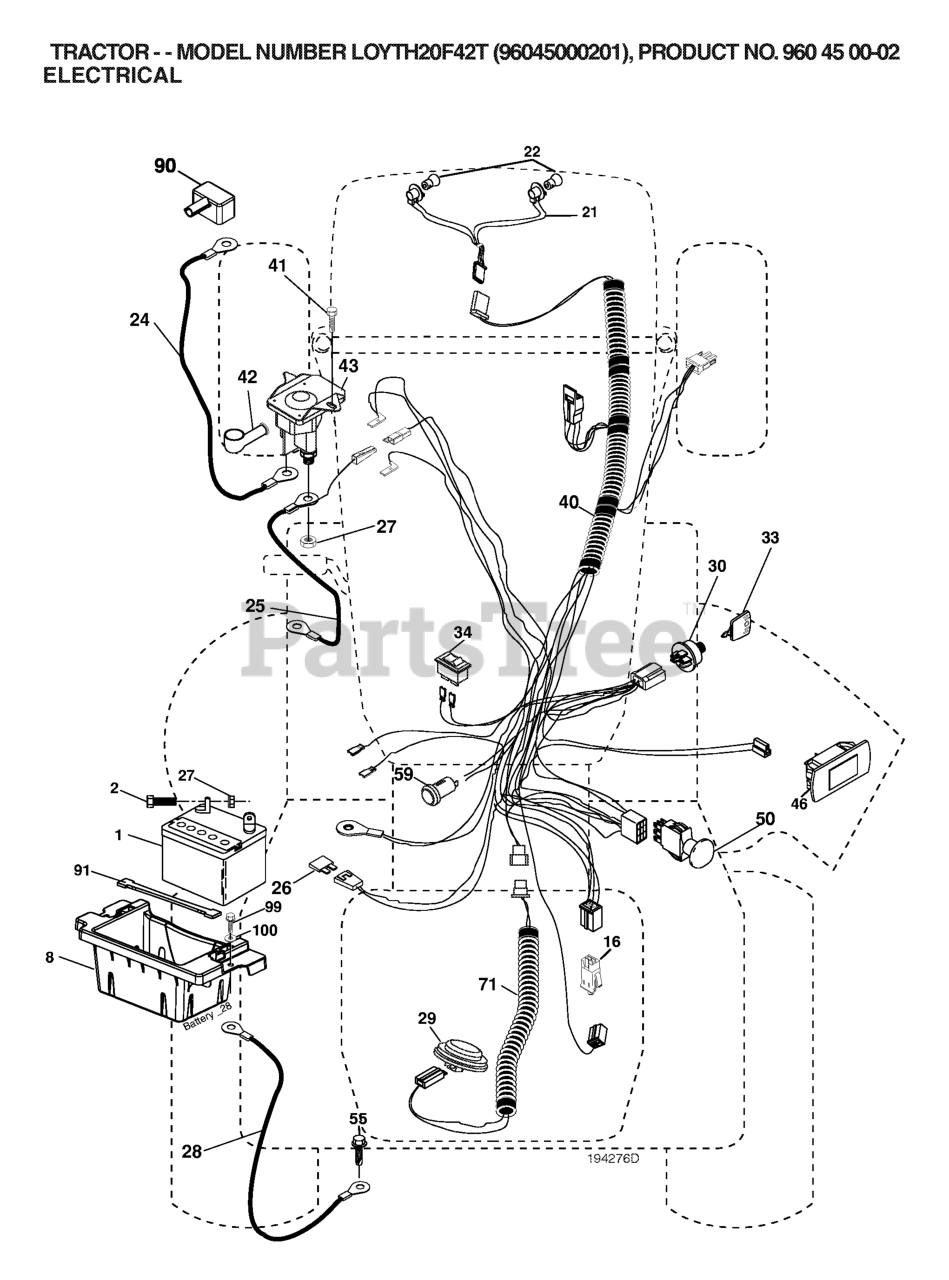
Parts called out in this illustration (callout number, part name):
1	BATTERY 12V .35 AMP
2	BOLT.HEX.1/4.X.3/4.DICHROMATE
8	BOX.BATTERY.MOUNT.FRONT.LT
16	SWITCH INTERLOOK PUSH-IN
21	HARNESS ASSY LIGHT
24	CABLE.BATT.POS.WIRE.TG.DA SOL
25	CABLE.START.RED.17.5".
26	FUSE 20AMP
27	NUT
28	CABLE GROUND 6 GA 21" 90T BLK
29	SWITCH.SEAT.DELTA.OPC.
30	SWITCH.IGN.DELTA.W.LGH.ROS
33	KEY MLD GEN DELTA
40	HARNESS-CHASSIS SUB
41	SCREW
42	TERMINAL COVER
43	SOLENOID.W/BRASS.PLUNGER
46	GAUGE.SERVICEMINDER.HR
50	RP.SWTICH.PTO.8.TERMINAL
55	SCREW.THDROL.5/16-18X3/4.TTY
71	HARNESS.IGN.DASH.HUQ/P
90	COVER.TERMINAL.BATTERY
91	STRAP.BATTERY.MOUNT.FRONT(2 2)
99	SCREW HEXWSHR 1/4-20X3/4
